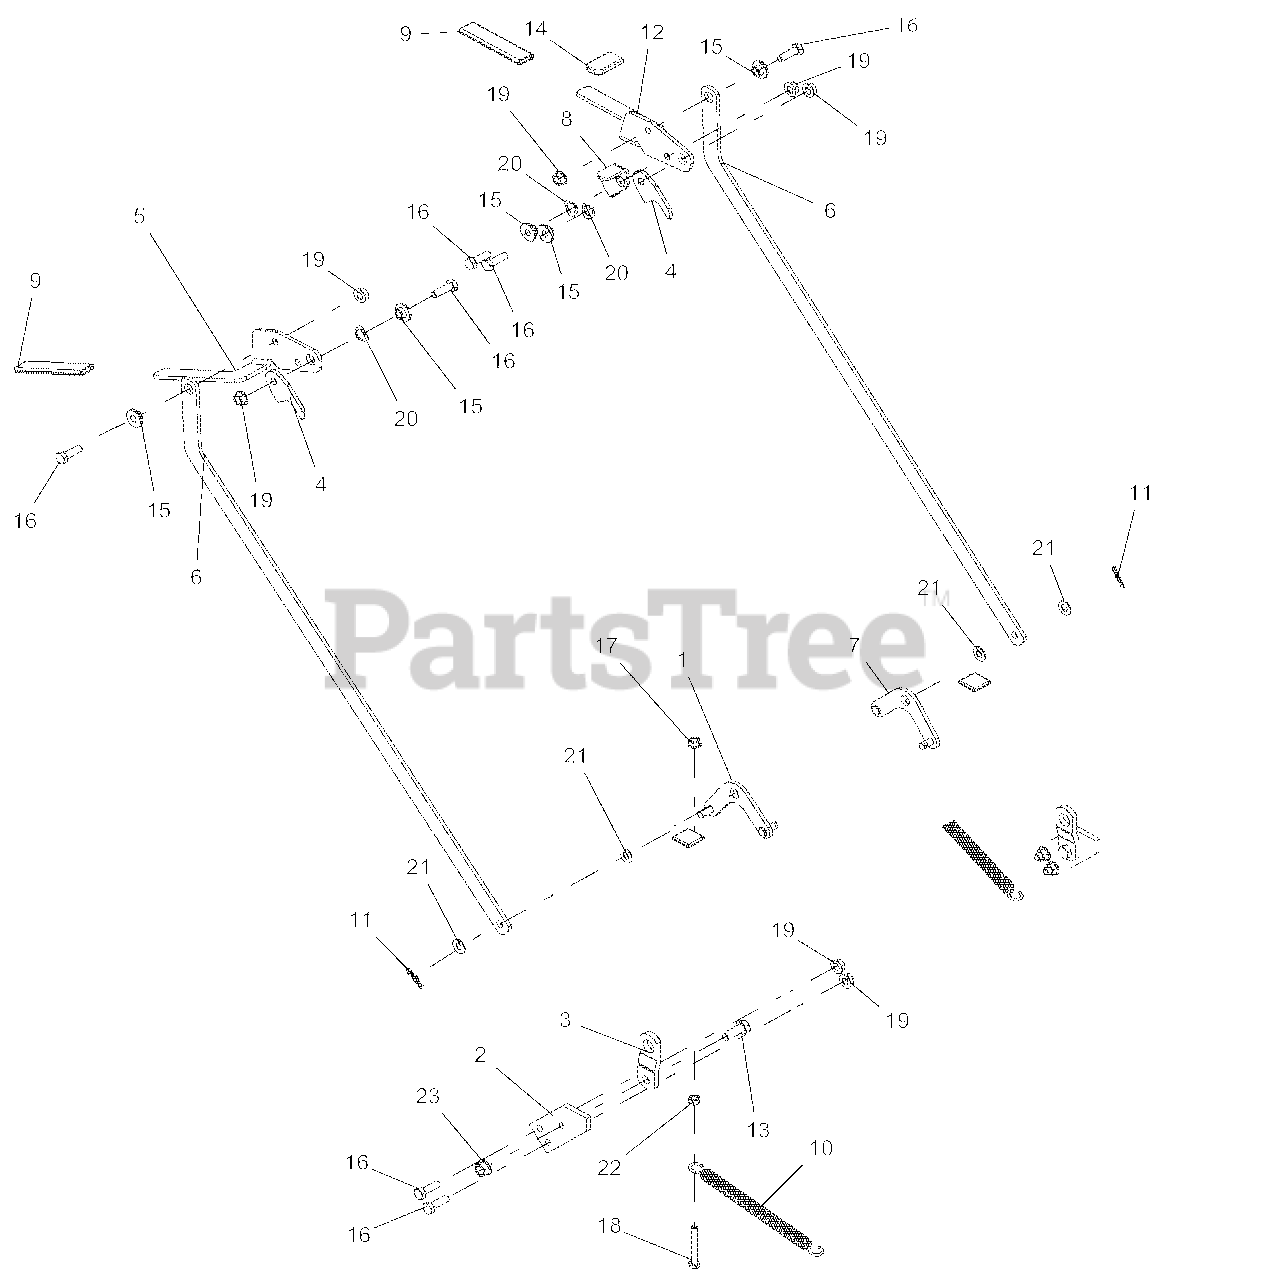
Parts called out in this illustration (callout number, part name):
1	WLDMT, BELL CRANK (BLACK)
2	PIVOT, SP FRAME
3	BRKT, SP FRAME PIVOT (BLACK)
4	MOUNT, SP ENGAGEMENT LEVER
5	LEVER, SP ENGAGEMENT (BLACK)
6	BAR, ENGAGEMENT LEVER CONN. (BLACK)
7	WLDMT, BELL CRANK, HWM BRAKE (BLACK)
8	LOCK, HWM PARK BRAKE (BLACK)
9	GRIP, MZR/MOMENT SP 7/8X3/4X4
10	SPRG, EXTENSION
11	PIN-HAIR, ENDRIES #25 YWZC
12	LEVER, SP ENGAGEMENT
13	BLT-HEX .38-16X1.00 GR5 YWZC
14	GRIP, THUMB LATCH
15	BSHG, FLG .32X.500.344X.880
16	BLT-HEX .31-18X1.00 GR5 YWZC
17	NUT, LK-TOP-FLG .25-20 YWZC
18	BLT-HEX .25-20X2.00 GR5 YWZC
19	NUT, LK-TOP-FLG .312-18 YWZC
20	WSHR, WAVE .50X.75X.015 .13FRHT
21	WSHR-FL-STL.344X.688X.065YWZC
22	NUT-HEX .25-20 YWZC
23	NUT, LK-TOP-FLG .38-16 YWZC
